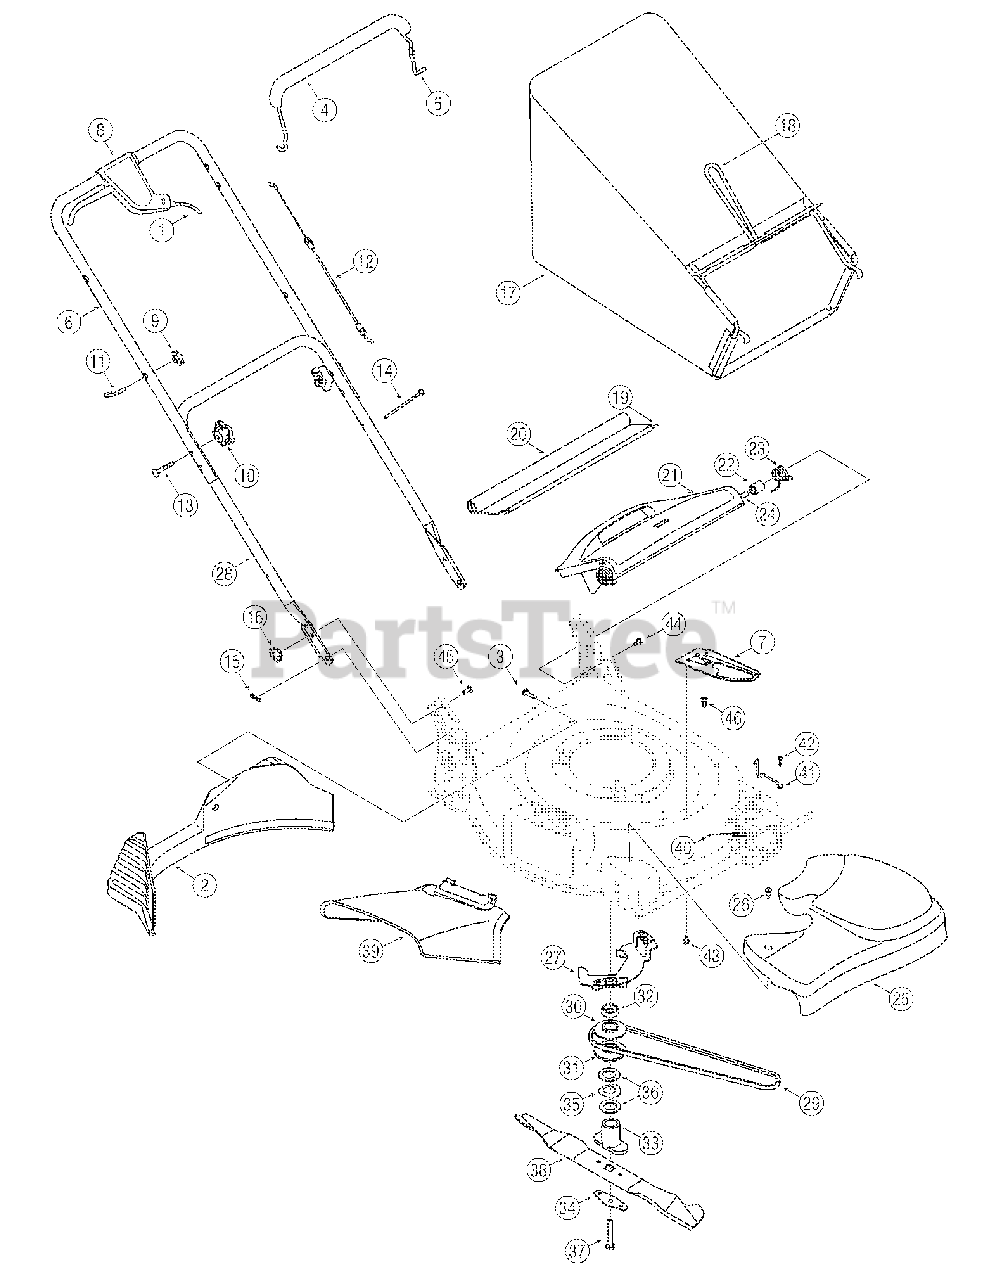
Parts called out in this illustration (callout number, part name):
1	Variable Speed Cable
2	Rear Baffle 21" Rd.
3	Screw 1/4-15
4	Deluxe Bail Cover
8	Control Lever Assembly
9	Handle Knob
10	Star Knob
12	Control Cable - 37.25"
13	Carriage Bolt 5/16-18 x 2.0
14	Cable Tie
15	Cotter Pin
16	Wing Nut
17	Grassbag Assembly
19	Wire
20	Trailshield
21	Rear Discharge Door
22	Spacer
23	Torsion Spring - LH
23	Torsion Spring - RH
24	Pivot Rod
25	Transmission Cover (Black)
26	Shoulder Screw # 12 -24
29	V-Belt
30	Upper Pulley Half 25mm x 2.62
31	Lower Pulley Half 25mm x 2.62
32	Sleeve Spacer 25mm x 1.375 x .62
33	Blade Adapter
34	Bell Blade Support
35	Space Washer
36	Flat Washer
37	Hex Screw 3/8-24 x 2.50
38	21" Mulching Blade
39	Side Discharge Chute
40	Extension Spring
41	Belt Keeper Wire
42	Torx Screw
43	AB Screw 1/4-14 x .625
44	TT Screw 1/4-20 x 0.5
45	Carriage Bolt 1/4-20
46	Shoulder Screw .375 x .25
